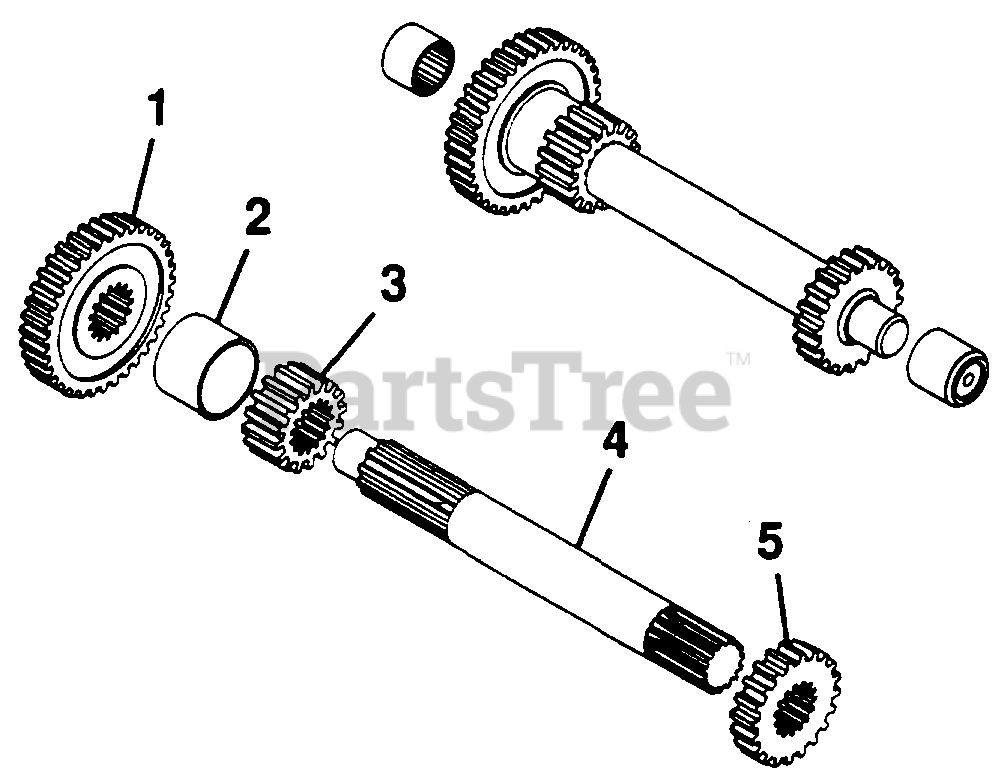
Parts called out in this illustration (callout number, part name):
1	GEAR, 10 DP 30 TEETH X .500
2	SPACER, 1.027X1.125X.550
3	GEAR, 10 DP 16 TEETH X.750
4	SHAFT, SPLINED
5	GEAR, 10 DP 20 TEETH X .600
